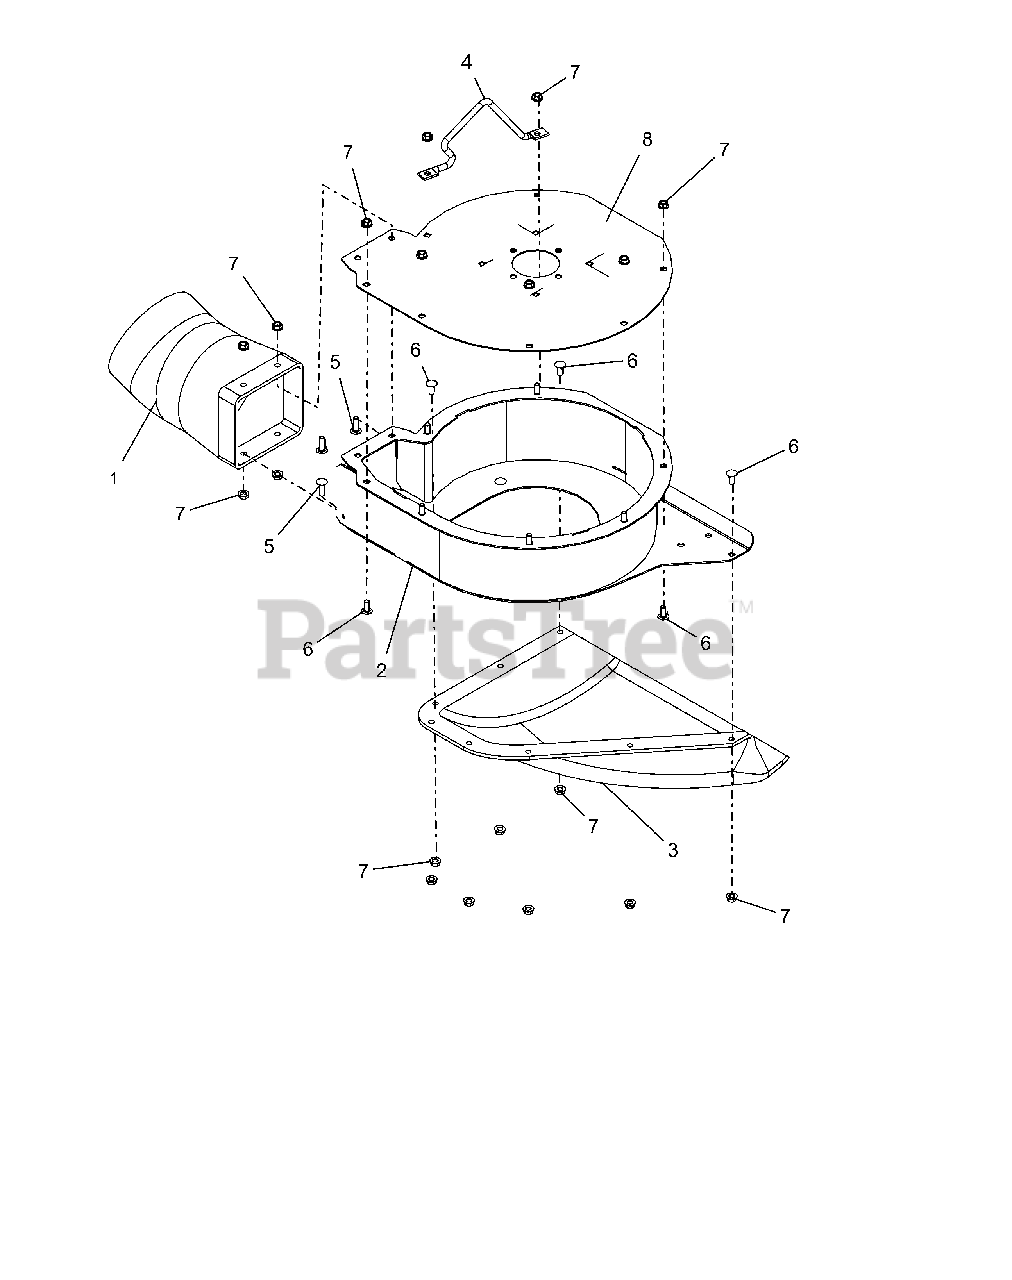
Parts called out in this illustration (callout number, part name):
1	ADAPTER, HOSE
2	WLDMT, HOUSING SCROLL (BLACK)
3	PLENUM, GRASS PUMP
4	HANDLE, BOLT-ON
5	@BLT-RHDSSQNK .31-18X1.00 G5YZ
6	@BLT-RHDSSQNK .31-18X.75 G5YZ
7	@NUT-LK-TOP-FLG .31-18 YWZC
8	PLT, BLOWER COVER (BLACK)
